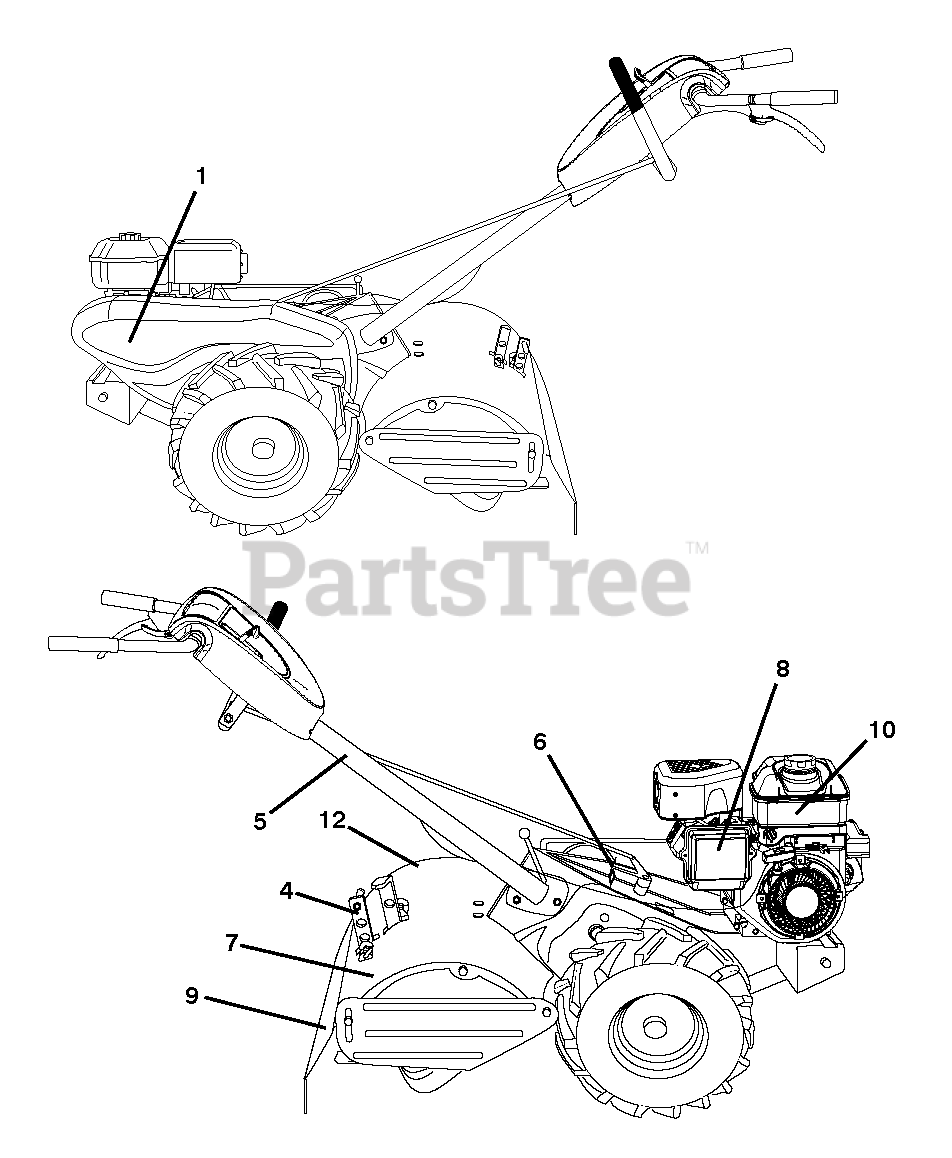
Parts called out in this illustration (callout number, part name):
1	RP.DECAL.BADGE.170MM.TEXTLOGO
4	DECAL.SHIELD.TN.DRT17.HUSQ
5	DECAL TI (2 2)
6	DECAL.SHIFT.INDICATOR.DRT
7	DECAL.REVERSE.HUSQ.TILLER
8	DECAL.B&S.900.A/S.C (279005)
9	DECAL.DRT.WARN.ENG/F
10	DECAL.B&S.900.TANK.REF.276991
12	DECAL.FOWARD.HUSQ.TILLER
